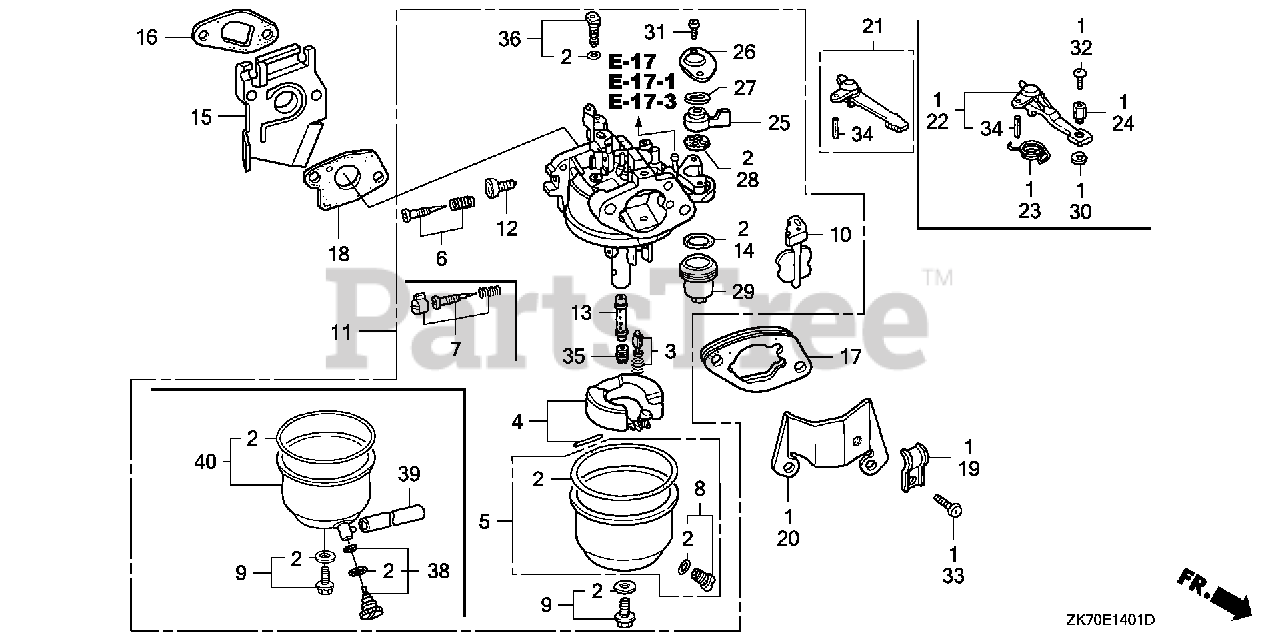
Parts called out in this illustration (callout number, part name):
2	GASKET SET
3	VALVE SET, FLOAT (SEAT NOT INCLUDED)
5	CHAMBER SET, FLOAT (CARBURETOR NO.)
7	SCREW SET, PILOT (CARBURETOR NO.)
8	SCREW SET, DRAIN
9	SCREW SET
10	CHOKE SET (CARBURETOR NO.)
11	CARBURETOR ASSY. (BE60C B)
12	SCREW, THROTTLE STOP
13	NOZZLE, MAIN (CARBURETOR NO.)
14	GASKET, FUEL STRAINER CUP
15	INSULATOR, CARBURETOR
16	GASKET, INSULATOR
17	SPACER, CARBURETOR
18	GASKET, CARBURETOR
21	LEVER, CHOKE (STD)
25	LEVER, PETCOCK
26	PLATE, LEVER SETTING
27	SPRING, PETCOCK LEVER
28	GASKET, PETCOCK
29	CUP, FUEL STRAINER
30	CIRCLIP (5MM)
31	SCREW, PAN (3X6)
34	PIN, SPRING (2X12)
35	JET, MAIN (#58) (CARBURETOR NO.)
35	JET, MAIN (#62) (CARBURETOR NO.)
35	JET, MAIN (#58)
35	JET, MAIN (#60)
36	JET SET, PILOT (#35)
